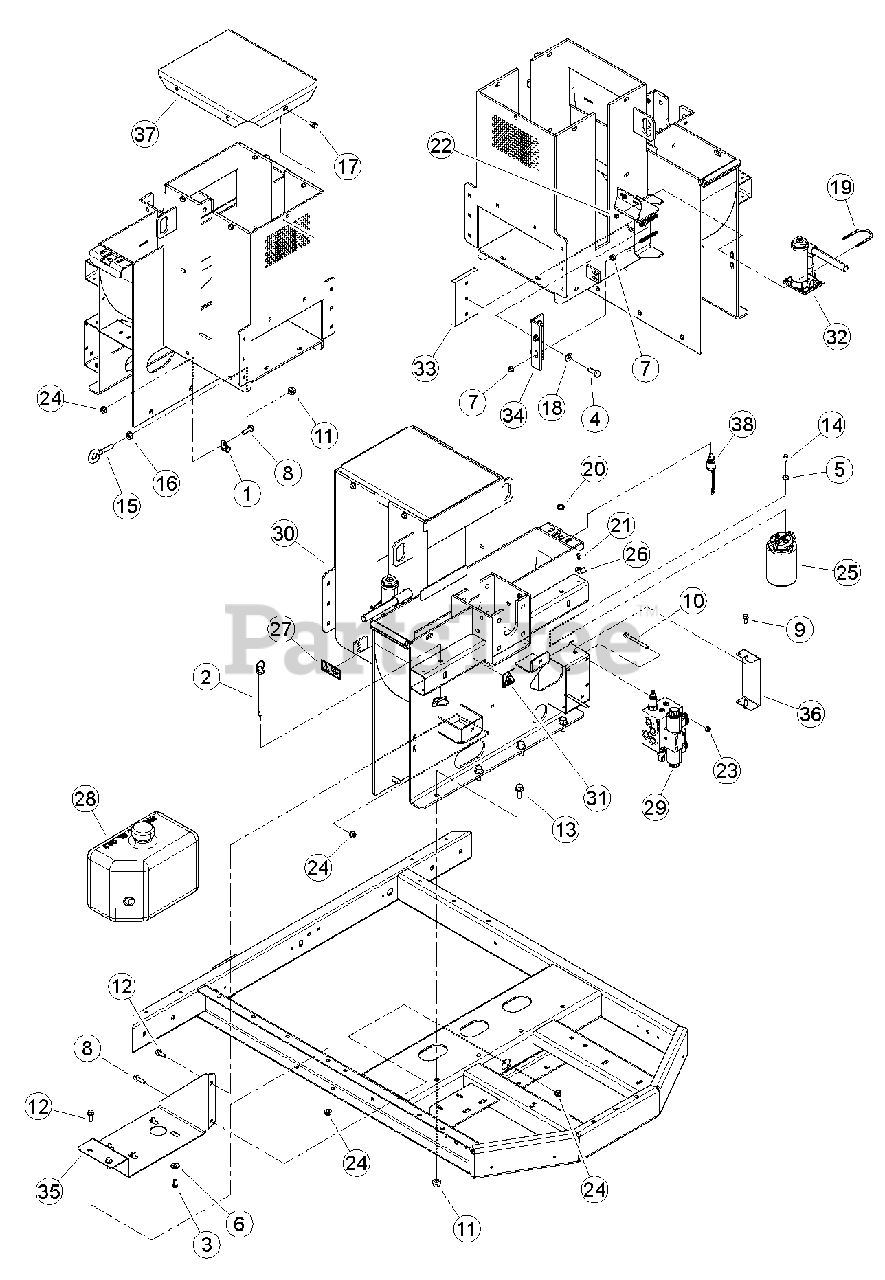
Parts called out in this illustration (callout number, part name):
1	CLAMP, 9/16 COATED
2	PIN, HITCH 1/2 X 6-1/2 W LYNCH
3	BOLT, 3/8 X 3/4 GR5 HEX CAPSCREW ZP
4	BOLT, 1/2 X 1-1/4" GR5 HHCS NC ZP
5	WASHER, 1/4 FLAT
6	WASHER, 3/8 FLAT
7	NUT, 3/8-16 SERRATED FLANGE
8	BOLT, 3/8 X 1-1/4 FLANGE NC
9	BOLT, 5/16 X 3/4 FLANGE NC
10	BOLT, 5/16 X 3-1/2 SERRATED FLANGE NC
11	NUT, 1/2-13 NYLOCK FLANGE
12	BOLT, 3/8 X 1 FLANGE NC
13	BOLT, 1/2 -13 X 1-1/4 FLANGE NC
14	BOLT, 1/4 X 5/8" HHCS GR5 ZP
15	EYEBOLT, 1/2-13 X 2
16	NUT, 1/2 SPIRAL LOCK NC ZP
17	BOLT, 3/8-16 X 3/4 SERRATED FLANGE
18	WASHER, 1/2 HI-STRENGTH SAE ZP
19	U-BOLT, 1/4 X 1-1/2 PIPE
20	NUT, 5/8-32 JAM
21	RIVET, AL BLIND 1/4 X 3/4 DOME HEAD
22	NUT, 1/4-20 NYLOCK FLANGE
23	NUT, 5/16-18 NYLOCK FLANGE
24	NUT, 3/8-16 NYLOCK FLANGE
25	ASSEMBLY, HYDRAULIC FILTER
26	CLAMP, CABLE MOUNT
27	DECAL, CRUSHING ISO
28	TANK, HYDRAULIC
29	ASSEMBLY, HYDRAULIC FEED FLOW VALVE W/ PS
30	ASSEMBLY, 6" CHIPPER HOUSING WITH DECALS
31	DECAL, SHIELD DANGER ISO
32	JACK, HYDRAULIC 2 TON
33	ANVIL, 6" CHIPPER
34	WELDMENT, BLOCK ADJUSTOR
35	BRACKET, HYDRAULIC TANK
36	COVER, CHIPPER SHAFT
37	WELDMENT, TOP ROLLER COVER
38	ASSEMBLY, SEALED SWITCH
